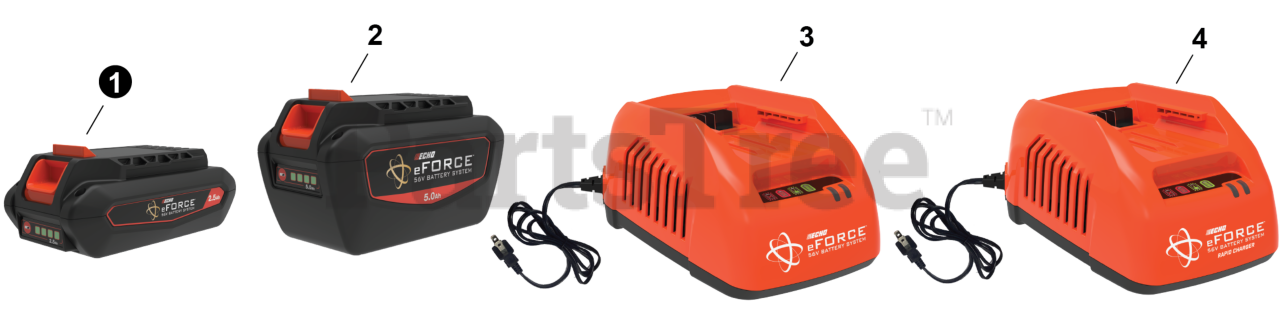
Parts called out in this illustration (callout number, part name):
1	BATTERY, 56V LITHIUM-ION - 2.5Ah
2	BATTERY, 56V LITHIUM-ION - 5.0Ah
3	CHARGER, BATTERY STANDARD 56V
4	CHARGER, BATTERY RAPID 56V
